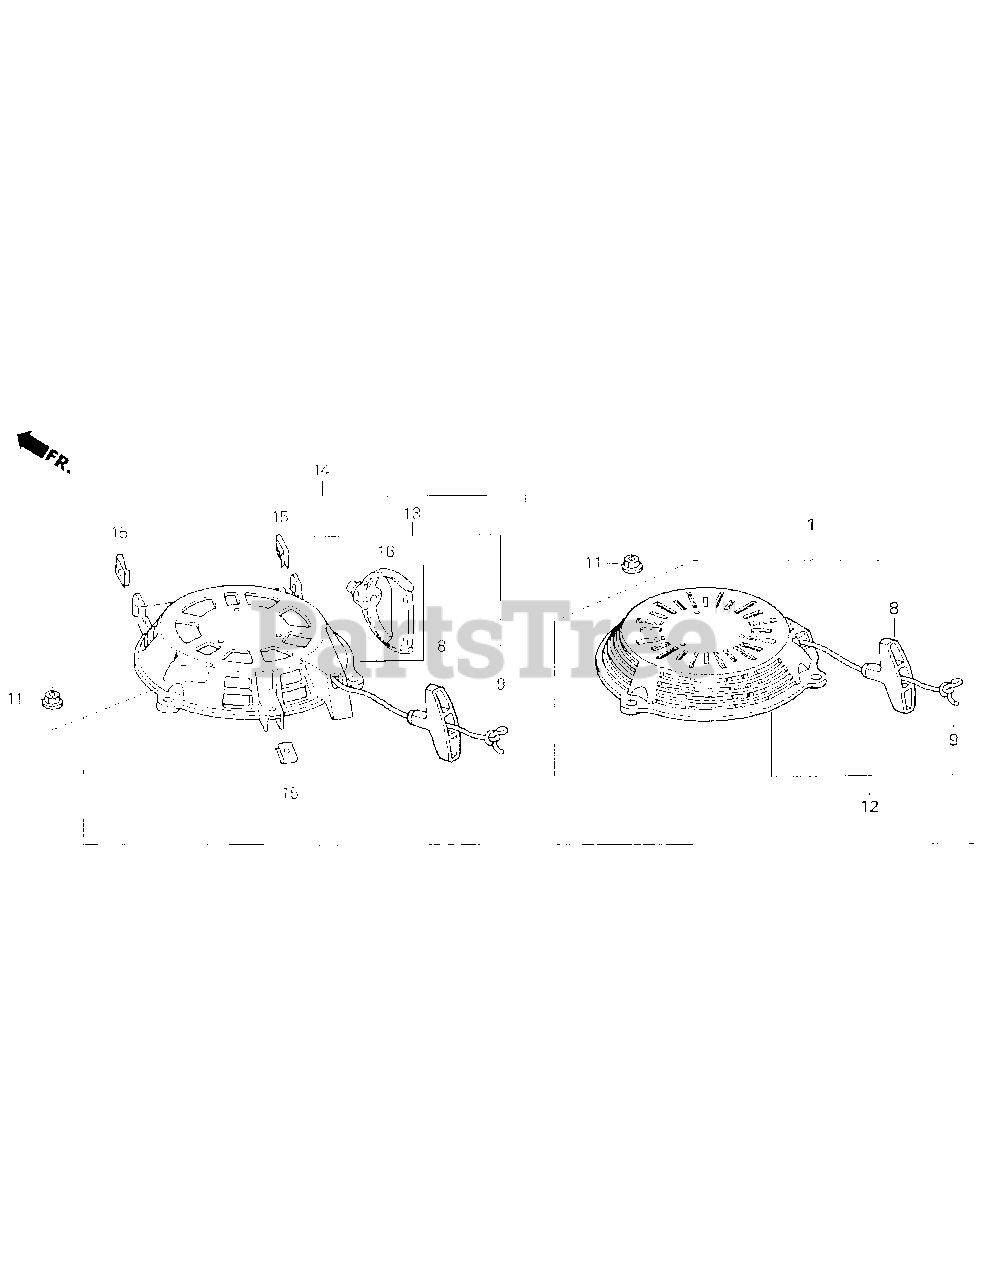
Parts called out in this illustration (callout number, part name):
1	STARTER ASSY., RECOIL *NH1* (BLACK)
8	KNOB, RECOIL STARTER
9	ROPE, RECOIL STARTER (#3.5X52")
11	NUT, FLANGE (6MM)
